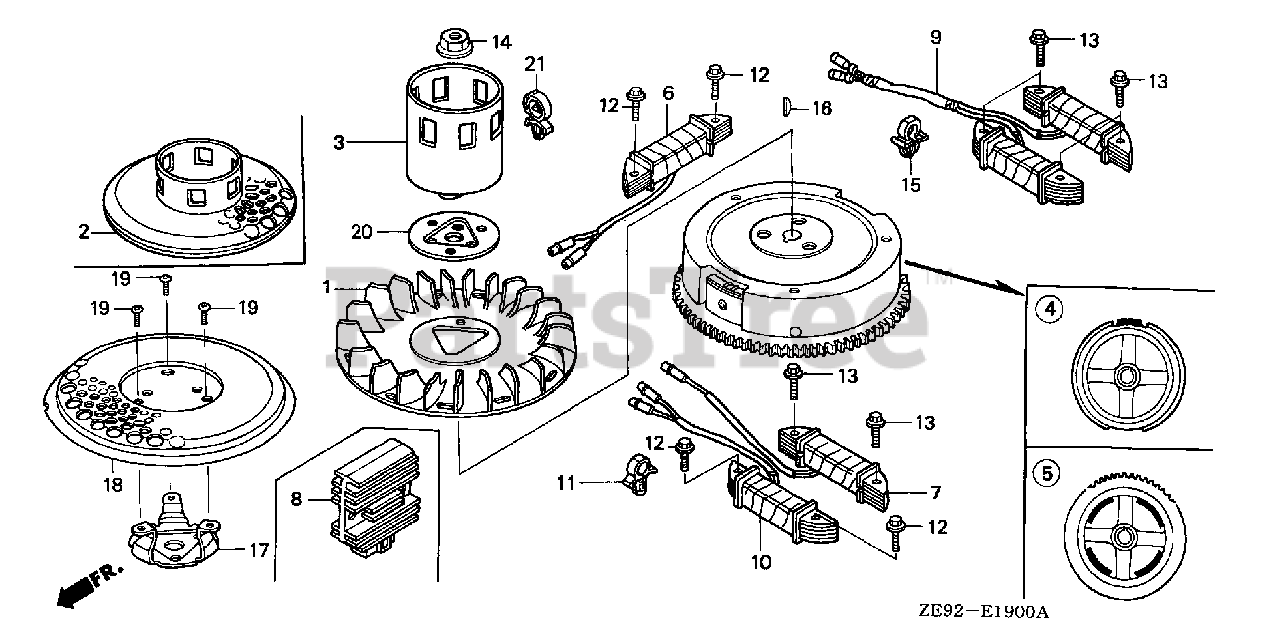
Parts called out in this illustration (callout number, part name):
1	FAN, COOLING
5	FLYWHEEL (SEL-4POLE)
6	COIL ASSY., CHARGE
11	CLIP, BRAKE PIPE (A)
12	BOLT, FLANGE (6X28) (CT200)
14	NUT, SPECIAL (16MM)
16	KEY, SPECIAL WOODRUFF (25X18)
